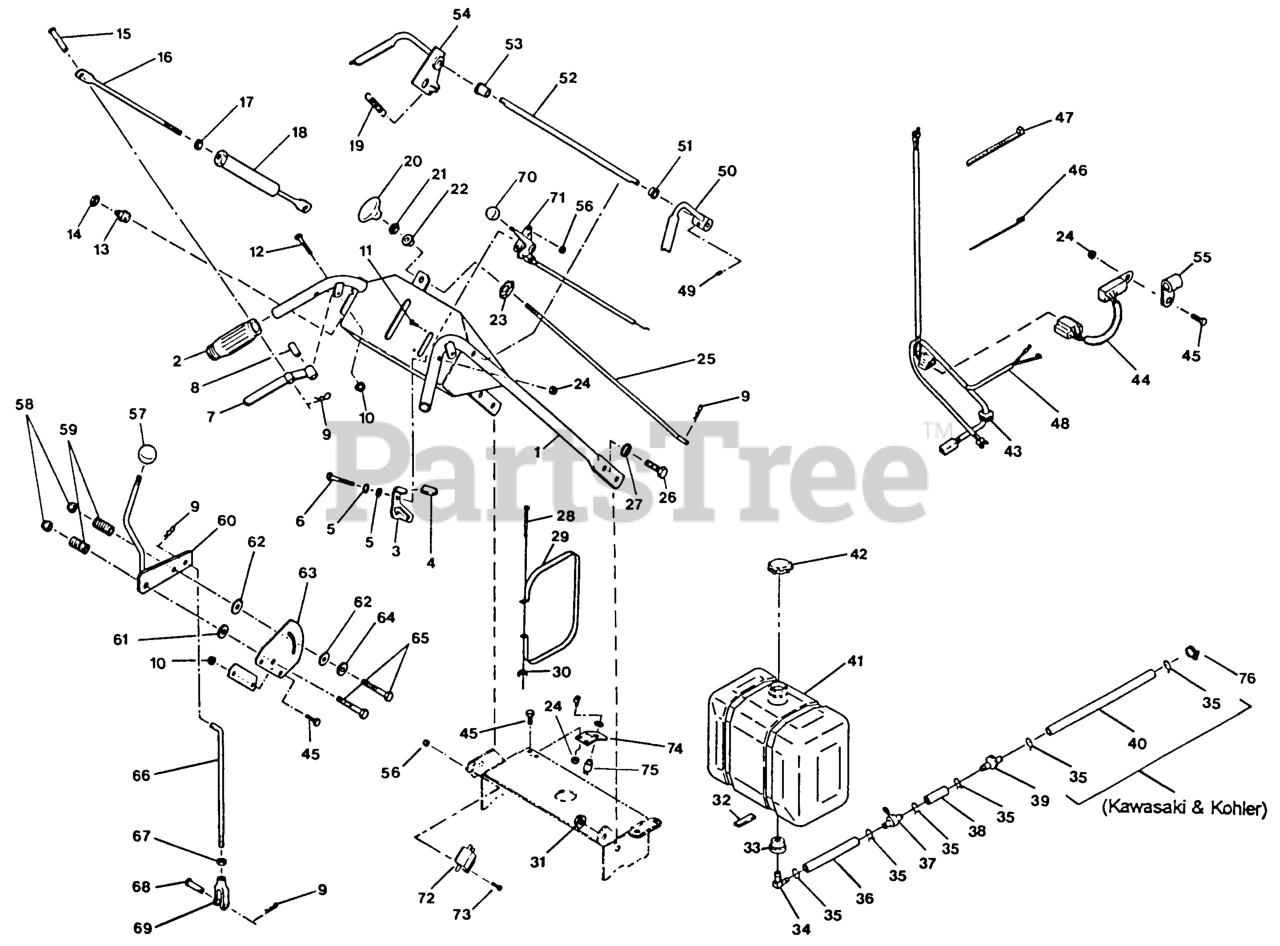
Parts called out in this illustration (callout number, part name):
4	GRIP-LATCH
5	WASHER-SPRING
8	BUSHING-LEVER, DRIVE
9	PIN-COTTER
11	BOLT-CARR
13	SWITCH,OPERATOR CNTRL
15	PIN - CLEVIS PLTD
16	ROD,DRIVE LEVER LINKAGE
19	SPRING-EXTENSION
20	KNOB-PUSH / PULL
22	BEARING-NYLON
23	NUT-PUSH
25	LINKAGE-BLADE
28	SCRW,MACH CRPH
30	WINGNUT
32	PAD,PLASTIC TANK
34	ELBOW-TANK, FUEL
36	HOSE-FUEL
37	VALVE-FUEL
38	HOSE-LINE, FUEL
40	HOSE-LINE, FUEL
42	CAP-FUEL
46	TIE-CABLE
47	TIE-PLASTIC
48	HARNESS,WIRING KAW
49	SCREW-SET
51	BUSHING-NYLON
52	ROD,CONNECTING
53	BUSHING,FLANGED
55	CLIP-LOOM
57	KNOB-BALL
59	SPRING-COMPRESSION
62	WASHER-FRICTION
63	PLATE-LEVER, SHIFTER
64	WASHER-FRICTION
66	ROD,SPEED CONTROL PLTD
68	PIN-CLEVIS
69	YOKE-ADJUSTABLE
70	KNOB-BALL
71	CABLE,THROTTLE CONTROL
72	SWITCH-OPEN, NORMALLY
75	SWITCH & KEY (INCLUDES NU
76	CLAMP-HOSE
